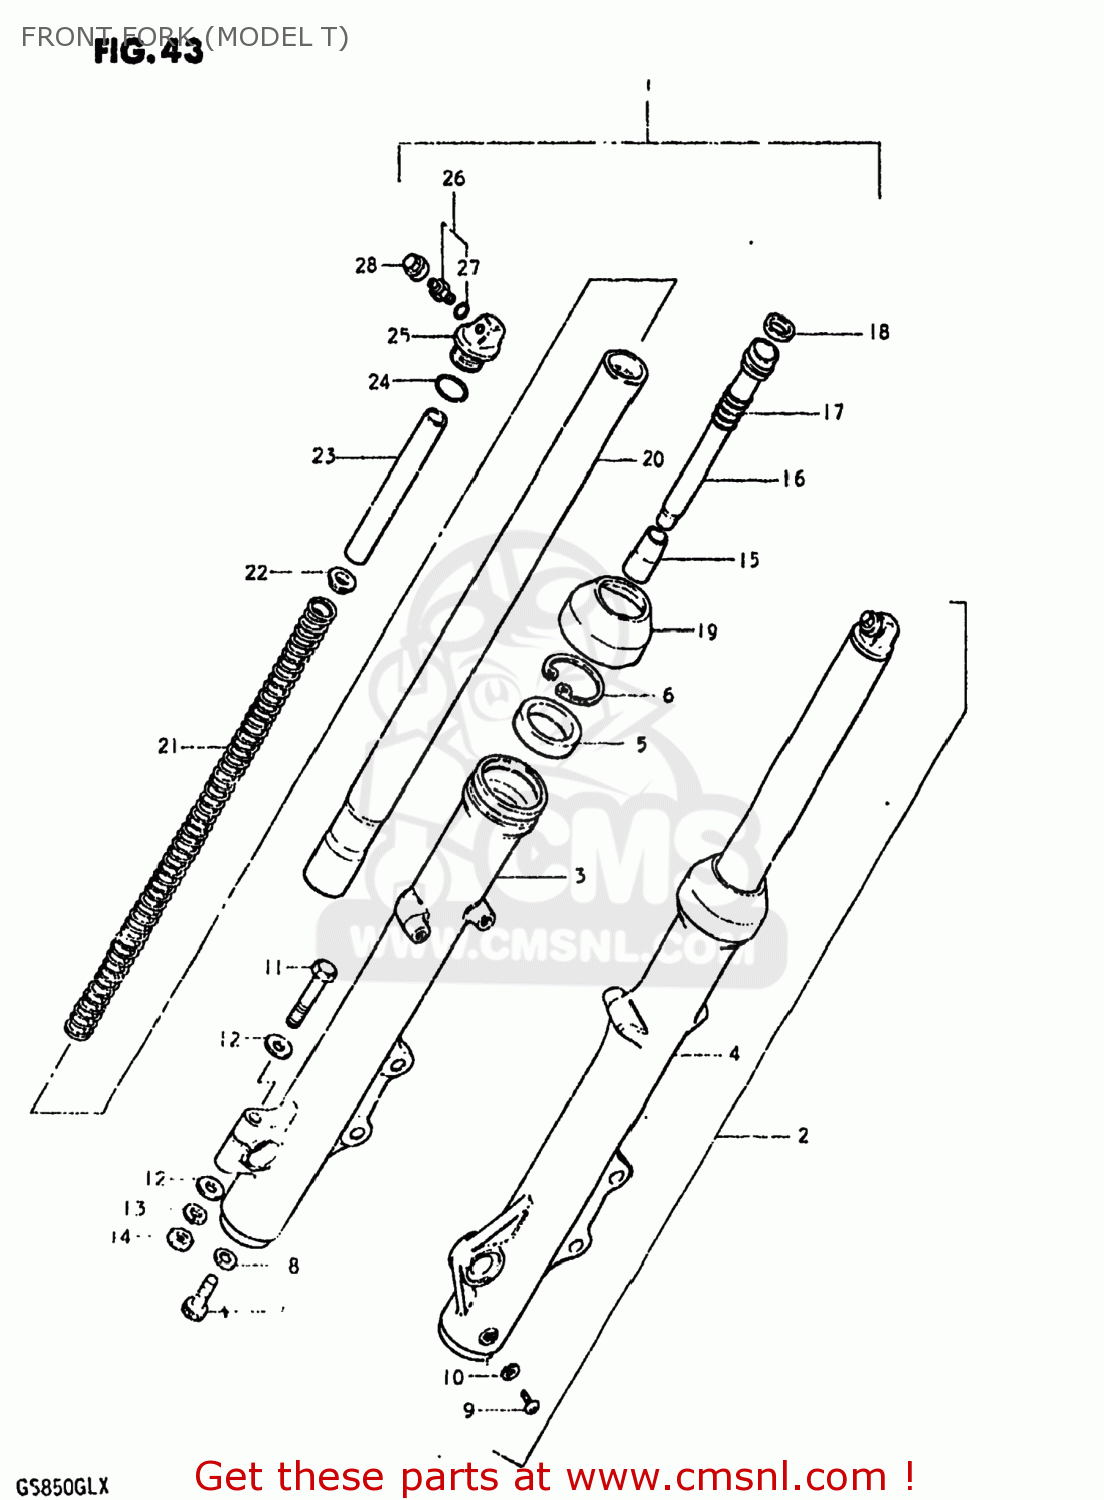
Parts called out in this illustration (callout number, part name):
1	DAMPER ASSEMBLY,RIGHT
2	DAMPER ASSEMBLY,LEFT
3	TUBE,FORK,OUTER,RIGHT
4	TUBE,FORK,LEFT,OUTER
5	OIL SEAL,FRONT FORK
6	RING,STOPPER
7	BOLT,FORK CYLINDER(10X25)
8	GASKET (NAS)
9	SCREW
10	GASKET,DRAIN,PLUG (NAS)
11	BOLT 8X50
12	WASHER
13	WASHER,LOCK,8.
14	NUT
15	PIECE,OIL LOCK
16	CYLINDER,FRONT FORK
17	SPRING,REBOUND
18	RING,PISTON
19	SEAL,DUST
20	TUBE,FORK,INNER
21	SPRING
22	GUIDE,FRONT FORK SPRING C
23	SPACER,SPRING
24	O RING
25	CAP
26	VALVE
27	O RING
28	CAP,VALVE
